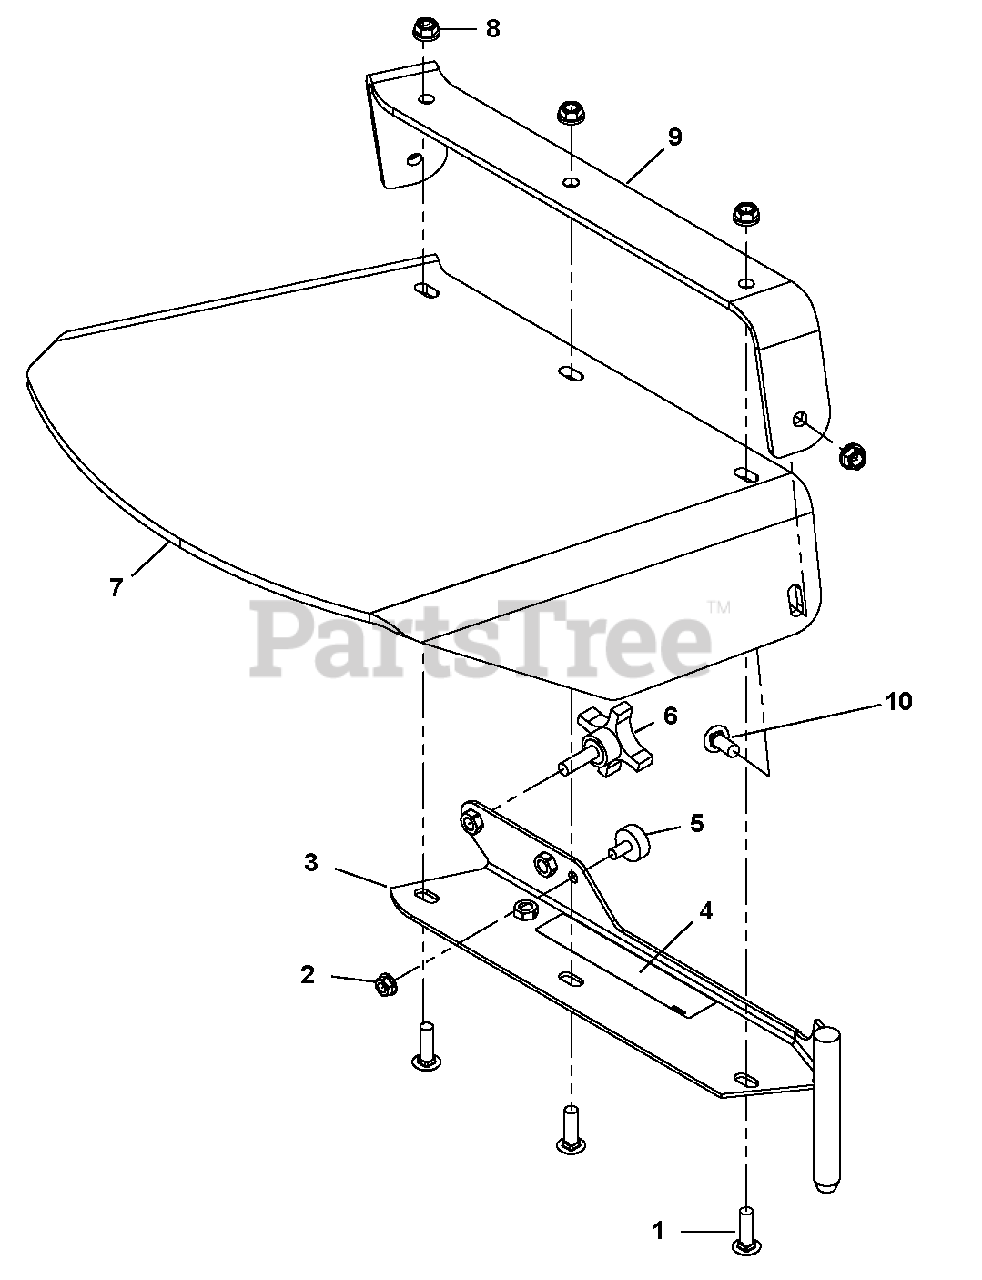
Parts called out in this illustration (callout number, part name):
1	Bolt, .38-16 x 1.25 Round Head Square Neck Grade 5
2	Locknut, .3125-18 WHIZ
3	Weldment, Discharge
4	Decal, Warning Rev C
5	Bumper, Rubber
6	Knob, .375 x 1.25 - 4 Prong
7	Shield, Walk Rubber Discharge
8	Nut, .375-16 Spring Lock Flange
9	Strap, Walk Rubber Discharge
10	Bolt, .38-16 x 1.0 Round Head Square Neck Grade 5
